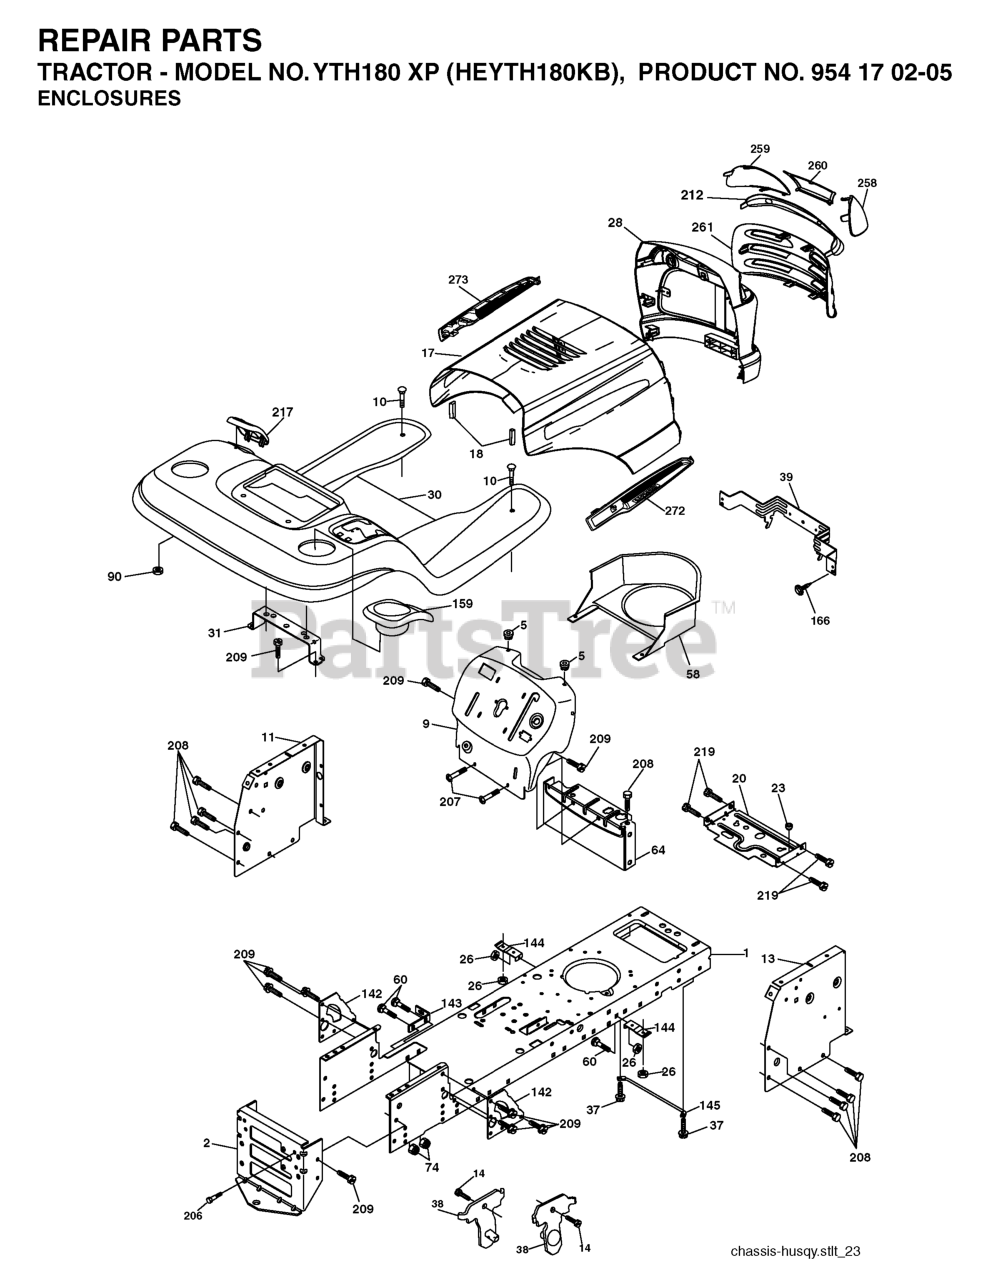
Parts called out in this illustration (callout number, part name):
1	CHASSIS STAMPING
2	DRAWBAR, 12GA
5	BUMPER.RUBBER.HOOD
10	BOLT D
11	PANEL.DASH.LH.LTX
13	PANEL ASM, DASH RH
17	VENT.HOOD.LASER.III
18	BUMPER.HOOD.LARGE.1.75"
20	PLATE MTG.BATTERY/FUEL TANK
23	BUSHING.SNAP.NYL.BLK.
26	NUT
30	FENDER
31	BRACKET.SUPPORT.FENDER
37	Screw 5/16-18 x 1/2 Hex, Self Tapping 5/16-18 x 1/2
38	BRACKET.ASM.PIVOT.MOWER.REAR
39	BRACKET PIVOT LASER
60	Bolt - Rd. Hd. Sq. Neckiage 3/8 16 x 3/4
64	DASH LOWER
90	NUT.PUSH.3/16
142	PLATE REINFORCEMENT
143	BRACKET, SWAYBAR CHASSIS
144	BRKT, FOOT REST
145	ROD PIVOT CHASSIS/HOOD
159	GREY CUP HOLDER
166	SCREW
206	SHOULDER BOLT 5/16-18TT
207	SCREW, 5/16-18 X 1/2
208	SCREW 3/8-16X1/2
209	SCREW, 3/8-16X3/4
212	INSERT.LENS.REFLECTIVE
217	CONSOLE FUEL WINDOW
219	SCREW
258	LENS LH
259	LENS LH
260	COVER.LENS.HUSQ.LASER
272	VENT.HOOD.LASER.
273	VENT.HOOD.LASER.
